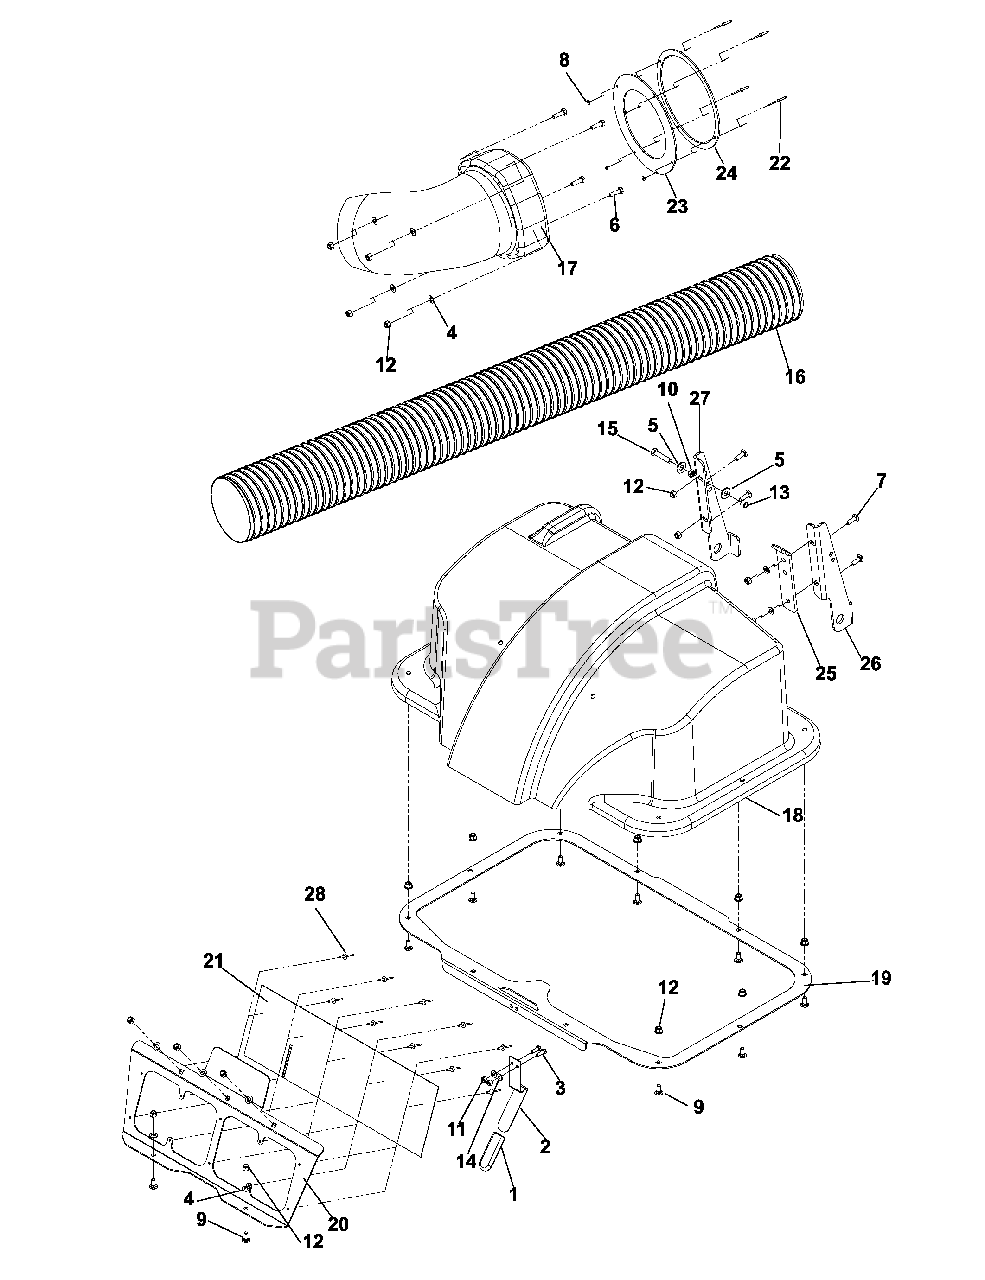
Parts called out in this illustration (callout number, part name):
1	LATCH ROD GRIP
2	G.C. CATCH HANDLE
3	HCS 1/4C X 3/4 HCS
4	FLAT WASHER 5/16 SAE
5	WASHER 3/8 FLAT
6	HCS 5/16C X 1
7	RHSSNB 5/16C X 1.0
8	WASHER .170 I.D.
9	BOLT 5/16C X 3/4" CARRIAGE
10	NUT 3/8-16 HEX JAM
11	NUT 1/4-20 NYLOC
12	NUT 5/16 NYLOC
13	NUT 3/8-16 NYLOC
14	1/4` SAE FLAT WASHER
15	HCS 3/8-16 X 1 3/4 GR5
16	FLEX HOSE 6 X 60
17	INLET TUBE
18	HOOD 2 BAGGER
19	HOOD BOTTOM PLATE
20	RETAINER SCREEN
21	VENT SCREEN
22	5/32 STEEL POP RIVET
23	BAGGER TUBE BOOT
24	BOOT BACKING PLATE
25	CLAMSHELL SUPPORT PLATE
26	RH HINGE PIVOT
27	LH HINGE PIVOT
28	LARGE DOME RIVET
